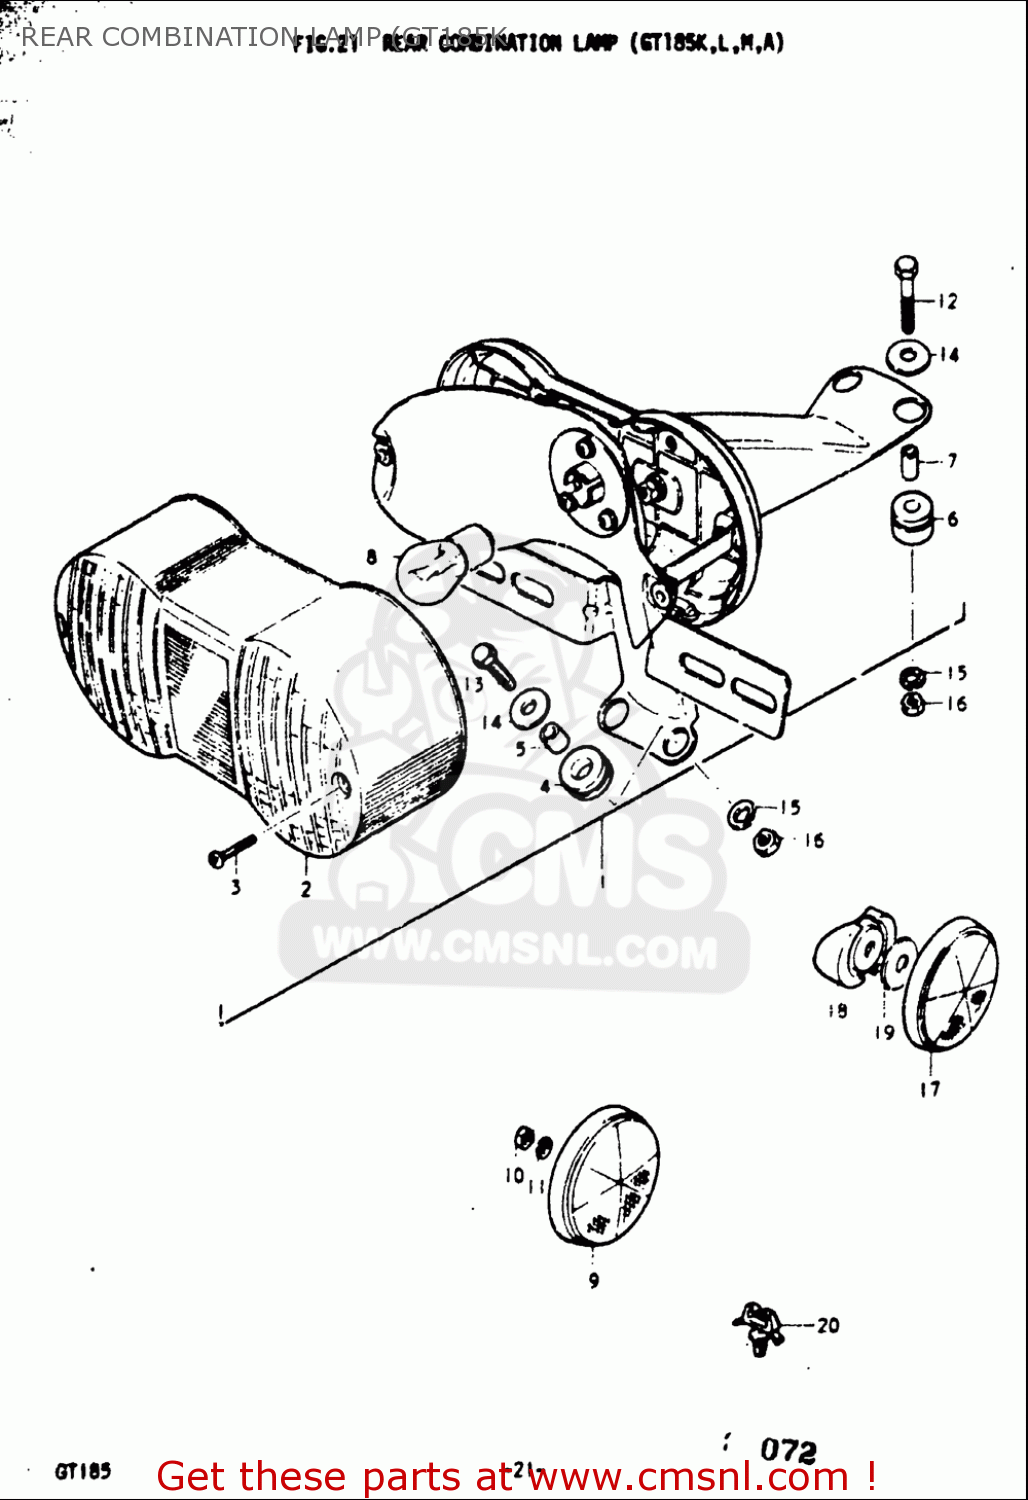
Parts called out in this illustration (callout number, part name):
2	LENS,RR COMBINATION LAMP
3	SCREW
4	CUSHION
5	SPACER
6	CUSHION
7	SPACER
8	BULB(12V23W)
10	NUT
11	WASHER,LOCK
12	BOLT
13	BOLT
14	WASHER(6.5X20X1.2)
15	WASHER,LOCK
16	NUT
17	REFLEX REFLECTOR,RR
18	SPACER
19	WASHER(6.5X20X1.2)
